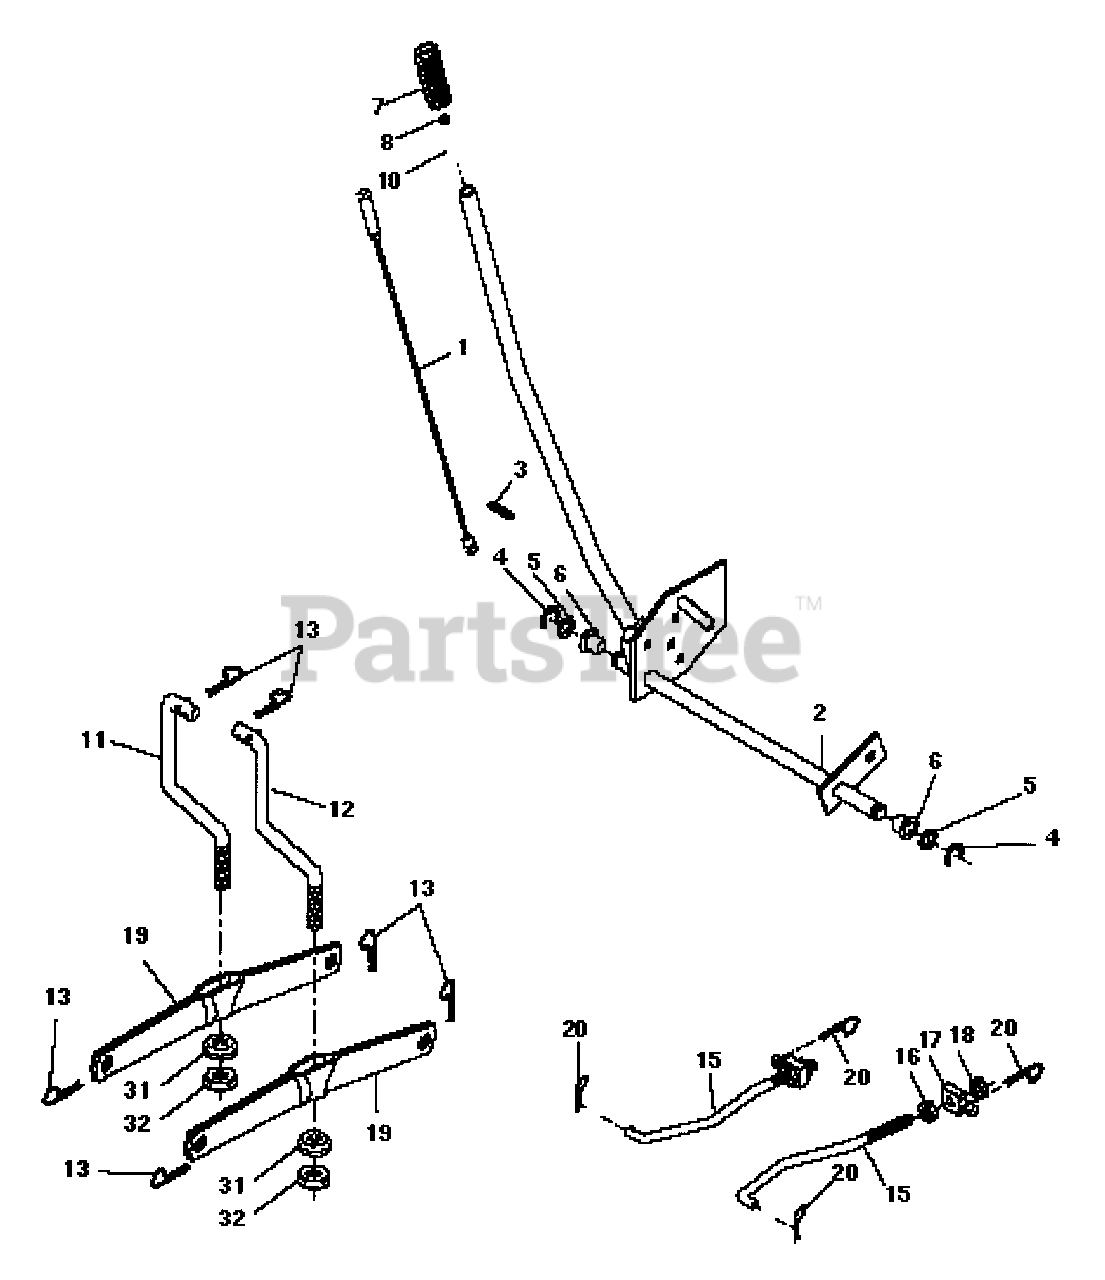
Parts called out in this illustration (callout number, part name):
1	Wire Asm Inner W/plunger 17 32
2	Shaft Asm Lift
3	Pin Groove
4	E Ring #5133-62
5	Washer PLTD 21/32 X 1 X 21ga
6	Bearing Nylon Blk 629 Id
7	Grip Handle Bicycle Matte Blk
8	Button Plunger Black
10	Spring Cprsn 3 750 Oiled
11	Link Lift LH
12	Link Lift RH
13	Retainer Spring
15	Link Front
16	Nut Jam Hex 1/2-13 Unc
17	Trunnion Blk Zinc
18	Nut Lock W/wsh 1/2-13unc
19	Arm Suspension Rear
20	Spring, Retainer
31	Bearing Pvt. Lift Spherical
32	Nut Crownlock 3/8-24
